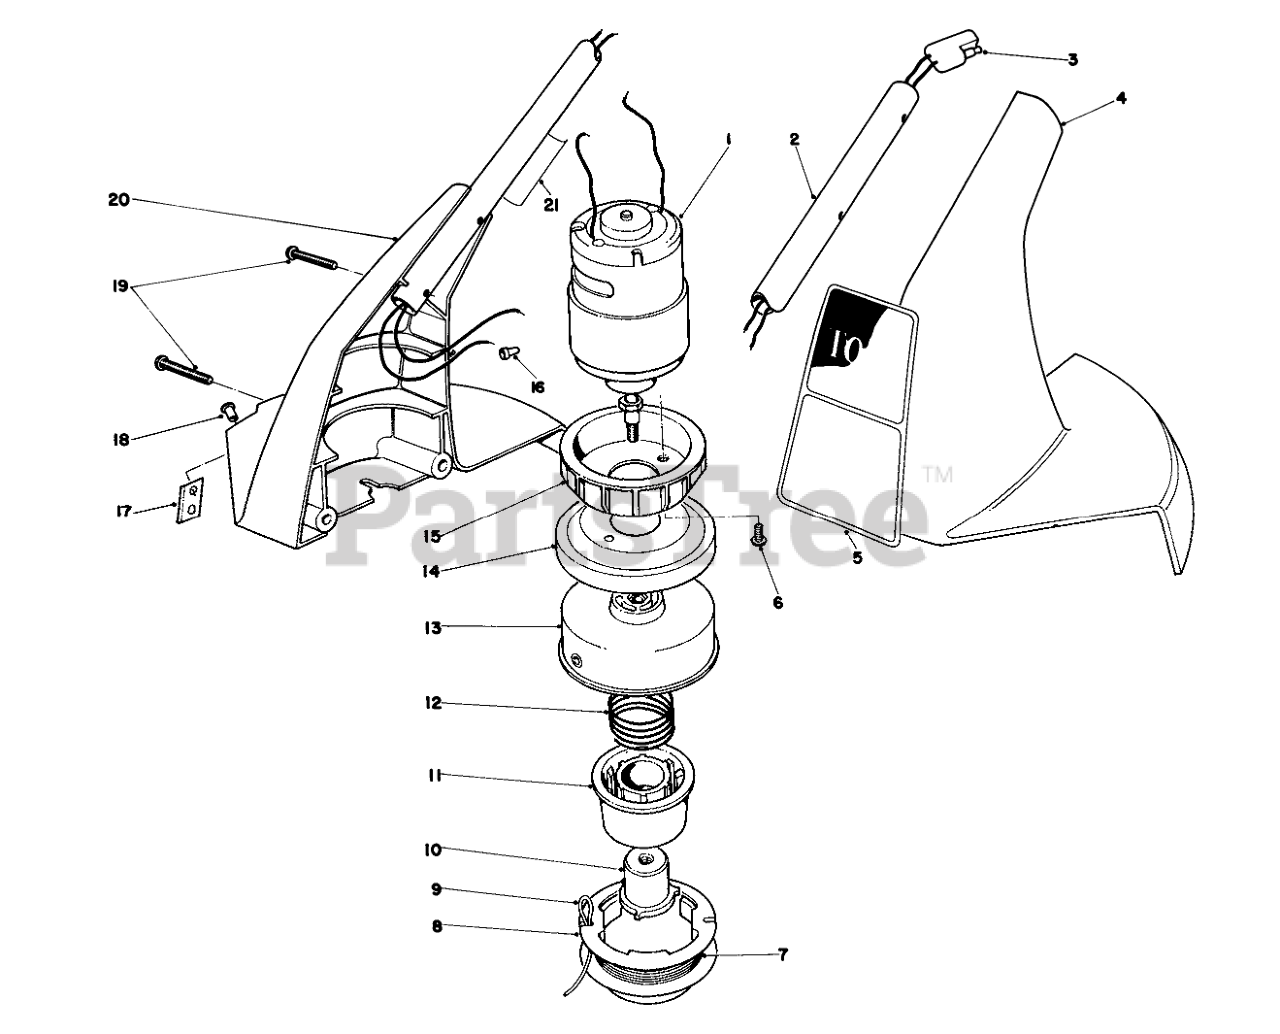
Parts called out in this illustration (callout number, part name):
1	Motor
2	EXTENSION HANDLE
3	WIRING HARNESS LOWER
4	Housing-L.H.
5	Decal-Housing
6	Screw
7	Prewound Spool
8	SPOOL CAP
9	.040" Cutting Line in Coil
10	DRIVER
11	CORE - SPOOL
12	Spring
13	Drum w/Eyelet
14	DRUM CUP
15	Casting-Heat Sink
16	Connector
17	Knife Blade
18	Rivet
19	SCREW-PLASTITE
20	R.H. Motor Housing (Incl. Ref. #17 & 18)
21	Decal
